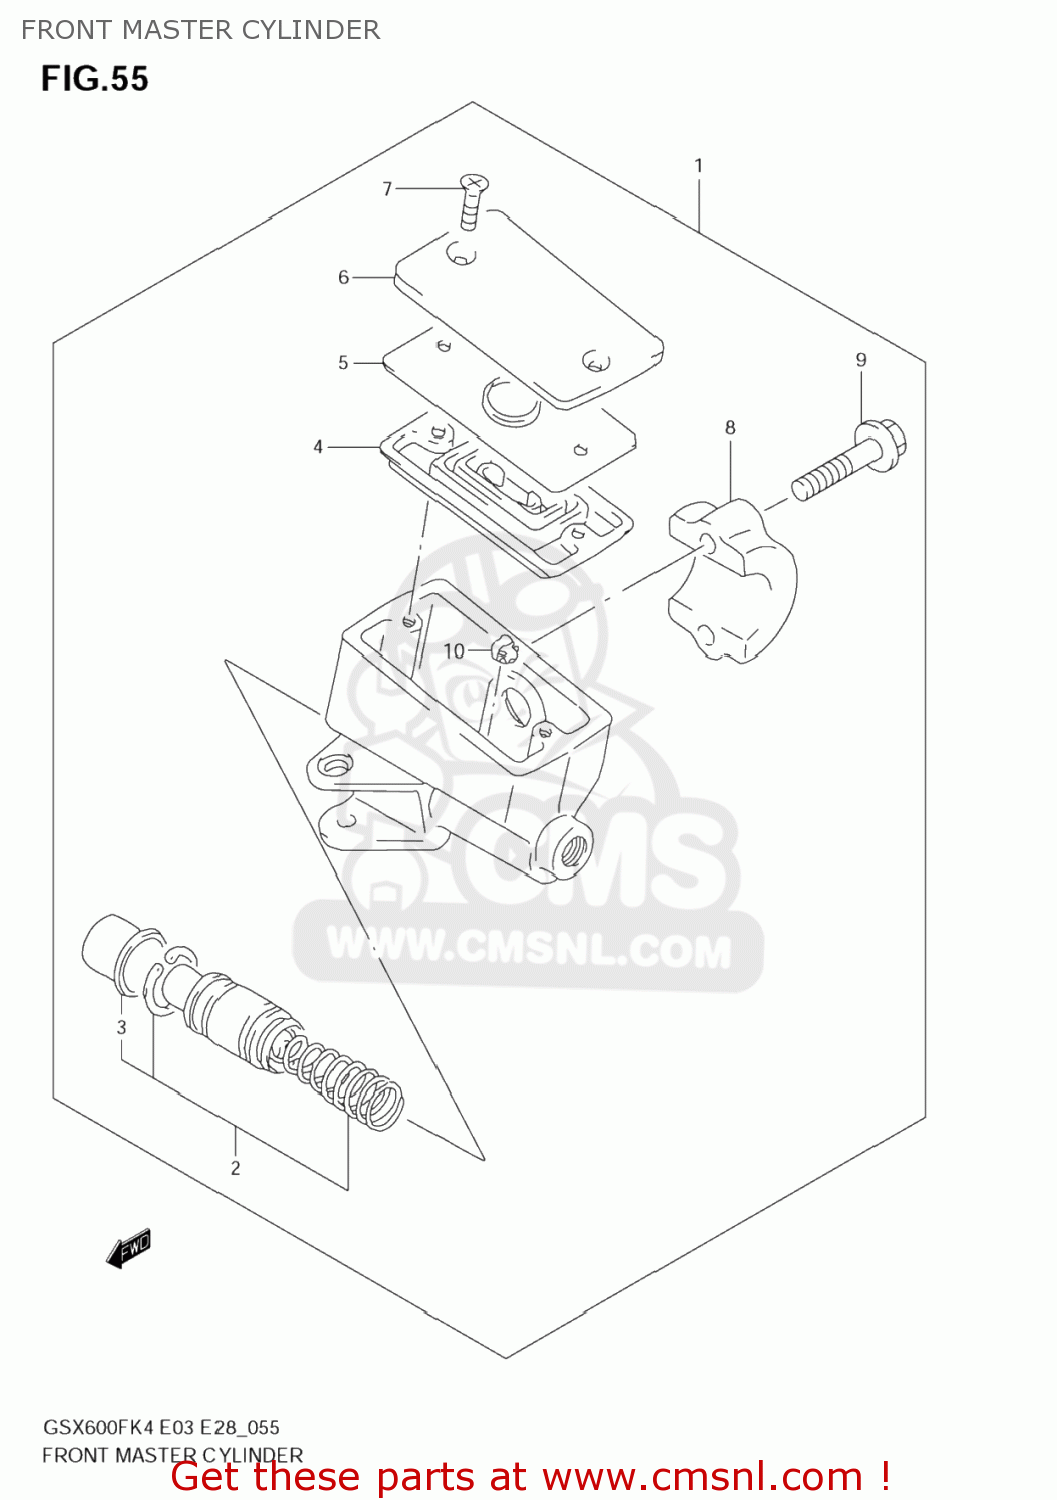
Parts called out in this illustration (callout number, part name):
1	CYLINDER ASSY,FR MASTER
2	PISTON & CUP SET
3	BOOT
4	5
5	PLATE,DIAPHRAGM
6	CAP
7	SCREW
8	HOLDER
9	BOLT(6X25)
10	PROTECTOR
